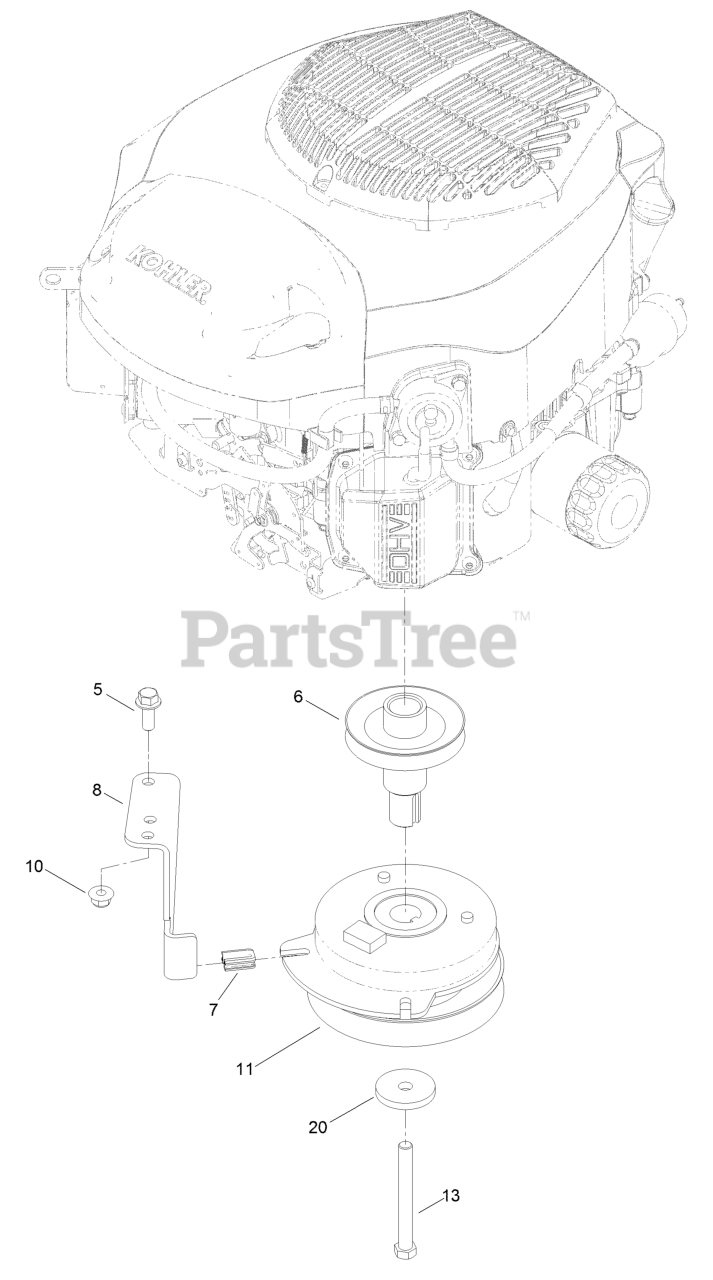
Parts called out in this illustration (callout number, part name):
5	SCREW-HHF 3/8-16 X 1
6	PULLEY-ENGINE
7	ISOLATOR-CLUTCH
8	STOP-CLUTCH
10	NUT-HF, NI
11	CLUTCH-PTO
13	SCREW-HH
20	WASHER-CLUTCH
